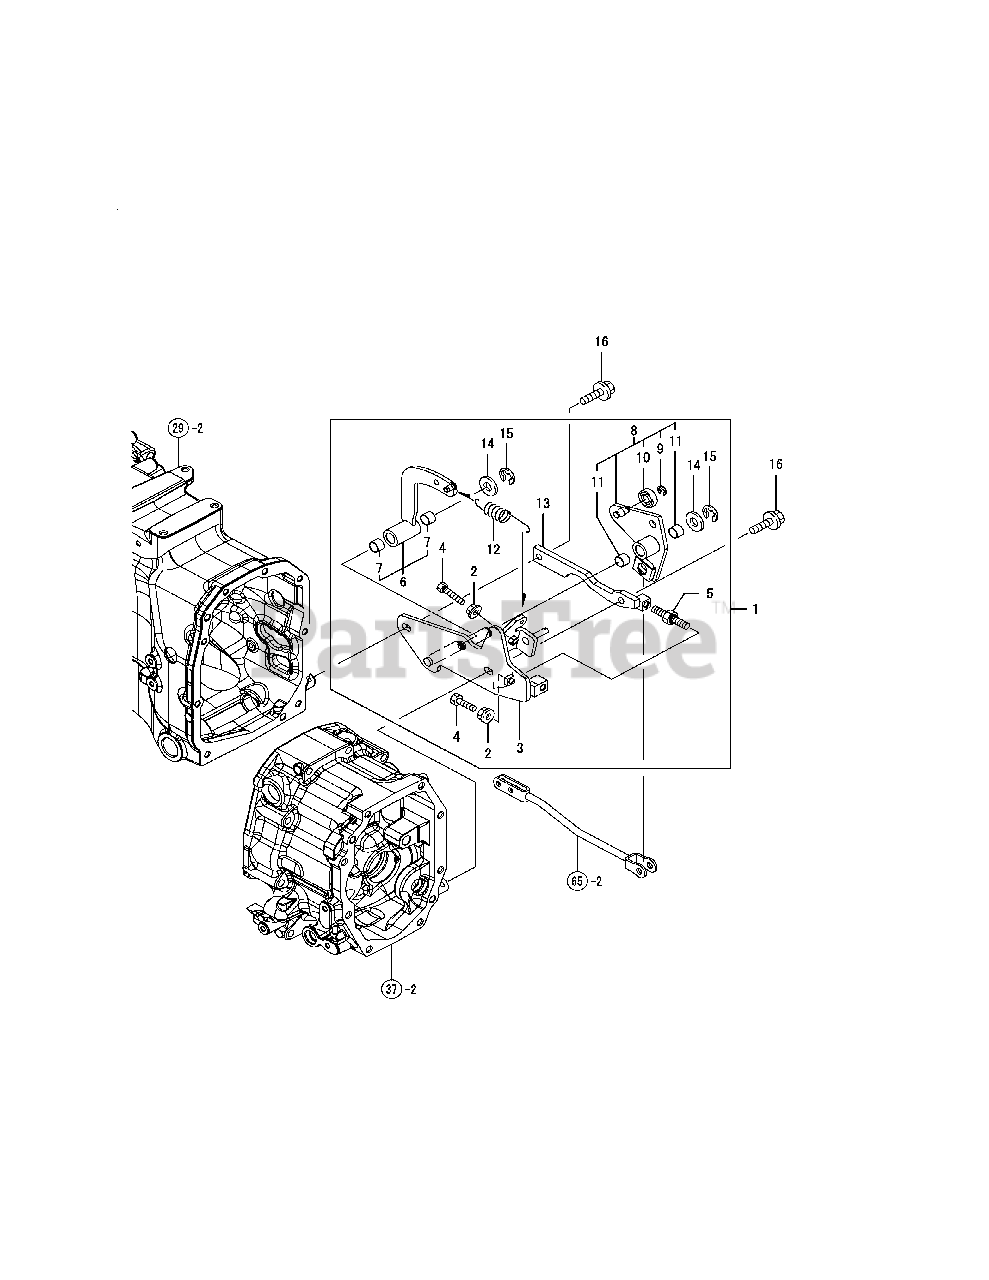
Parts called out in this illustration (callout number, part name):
1	NEUTRAL, HST ASSY
2	NUT W/WASHER 8
3	BRACKET, NEUTRAL CMP
5	TURNBUCKLE, NEUTRAL
6	ARM, RETURN ASSY
8	BRACKET, ROLLER ASSY
10	BEARING 6000UUC3
13	PLATE,ADJUST CMP
14	WASHER 14,POLISHED
16	BOLT M10X 30 PLATED
